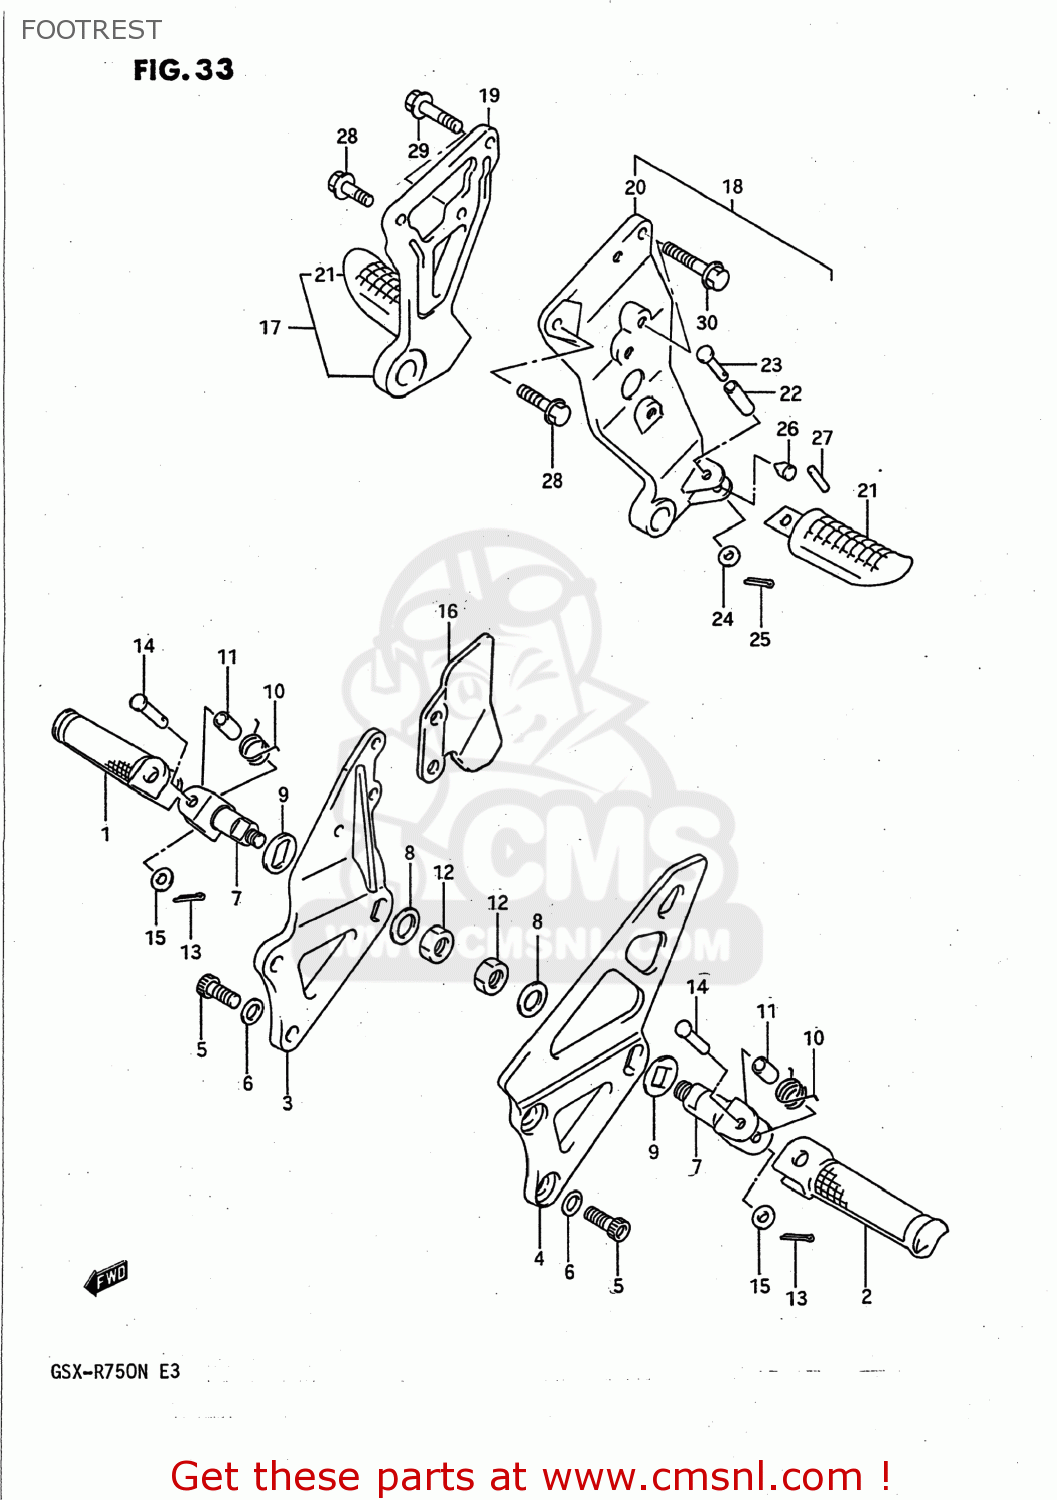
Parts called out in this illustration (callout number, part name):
1	BAR,FOOTREST,R
2	BAR,FOOTREST,L
3	BRACKET,FOOTREST,R
4	BRACKET,FOOTREST,L
5	BOLT,FOOTREST BRACKET
6	WASHER
7	BOSS,FOOTREST
8	PLATE,FOOTREST INNER
9	WASHER,FR FOOTREST
10	SPRING
11	SPACER(8.1X12X22)
12	NUT 12MM
13	PIN 20X15
14	PIN
15	WASHER(8.5X18X1)
16	GUARD,FRONT FOOTREST,RIGHT
17	FOOTREST ASSY,PILLION,R
18	FOOTREST ASSY,PILLION,L
19	BRACKET,PILLION FOOTREST
20	BRACKET
21	BAR,PILLION FOOTREST R
22	SPACER(8.1X12X22)
23	PIN
24	WASHER
25	PIN 20X20
26	CUSHION,FOOTREST HOLDER
27	ROLLER,FOOTREST HOLDER
28	BOLT
29	BOLT
30	BOLT 8X40
